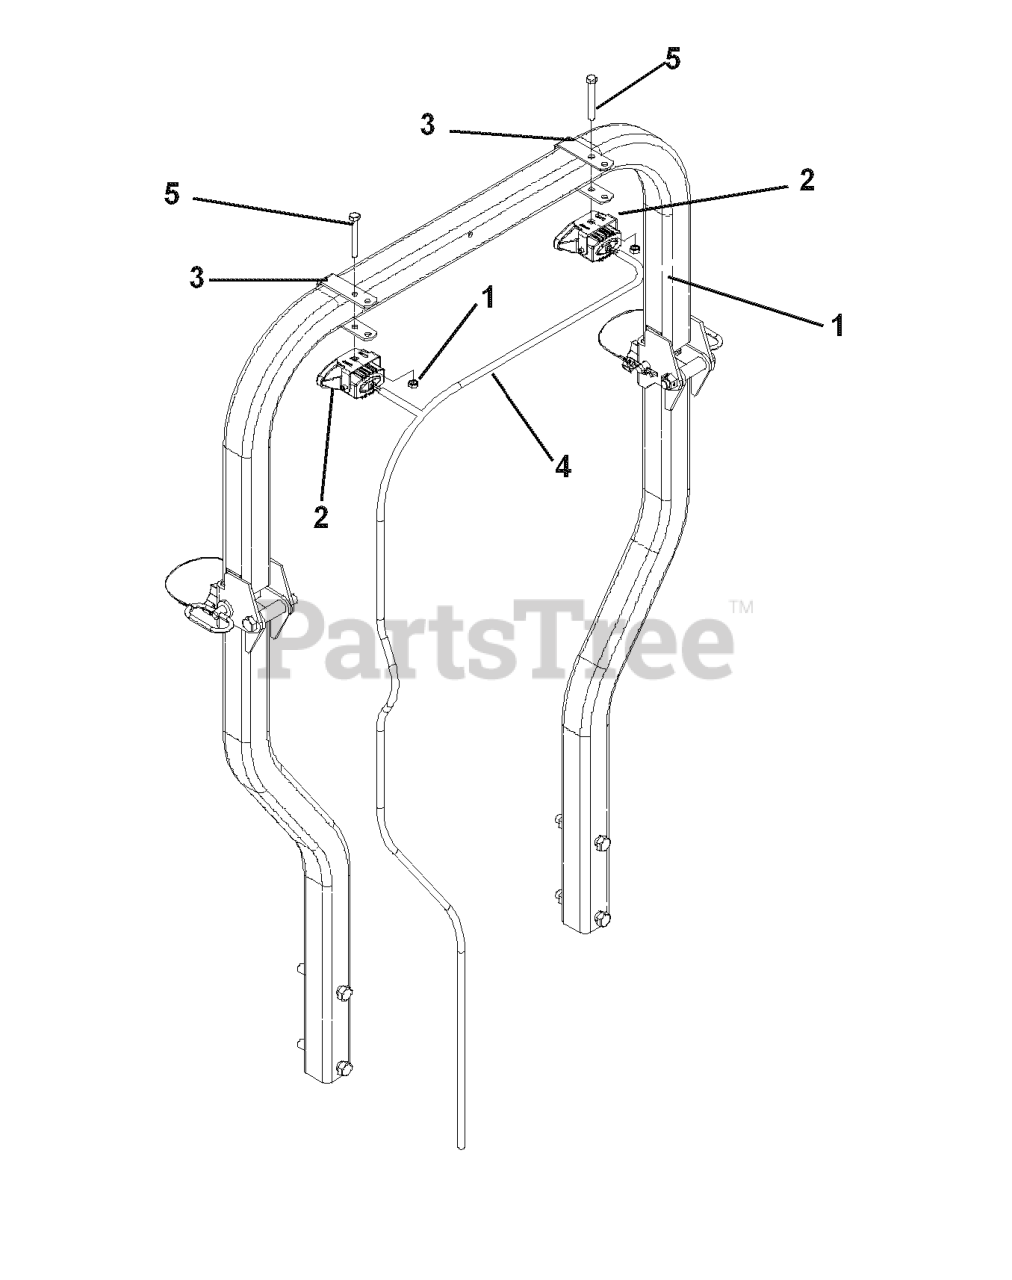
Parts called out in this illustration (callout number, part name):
1	NUT 5/16-18 HEX JAM ZD
2	LIGHT 35W W/BRKT
3	LIGHT MOUNTING BRACKET
4	LIGHT HARNESS
5	BOLT 5/16C X 2 1/2
